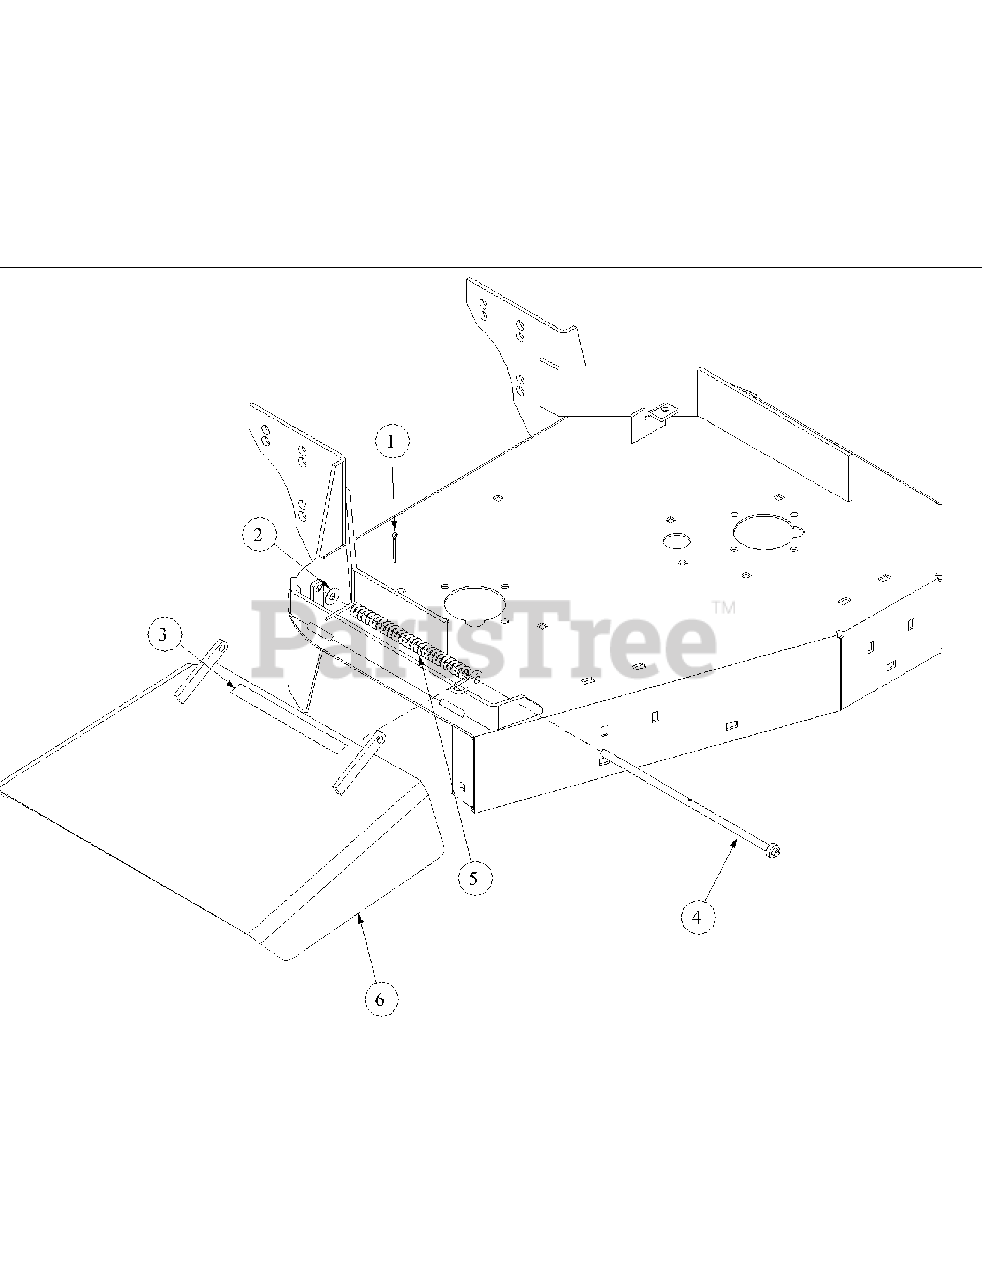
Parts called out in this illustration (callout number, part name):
1	Cotter Pin, 5/32 x 1 1/2 Zinc
2	Flat Washer, 3/8, Zinc
3	Decal, Cut Line
4	Pin, Deflector Assembly, Weldment1
5	Torsion Spring
6	Chute Assembly Discharge
